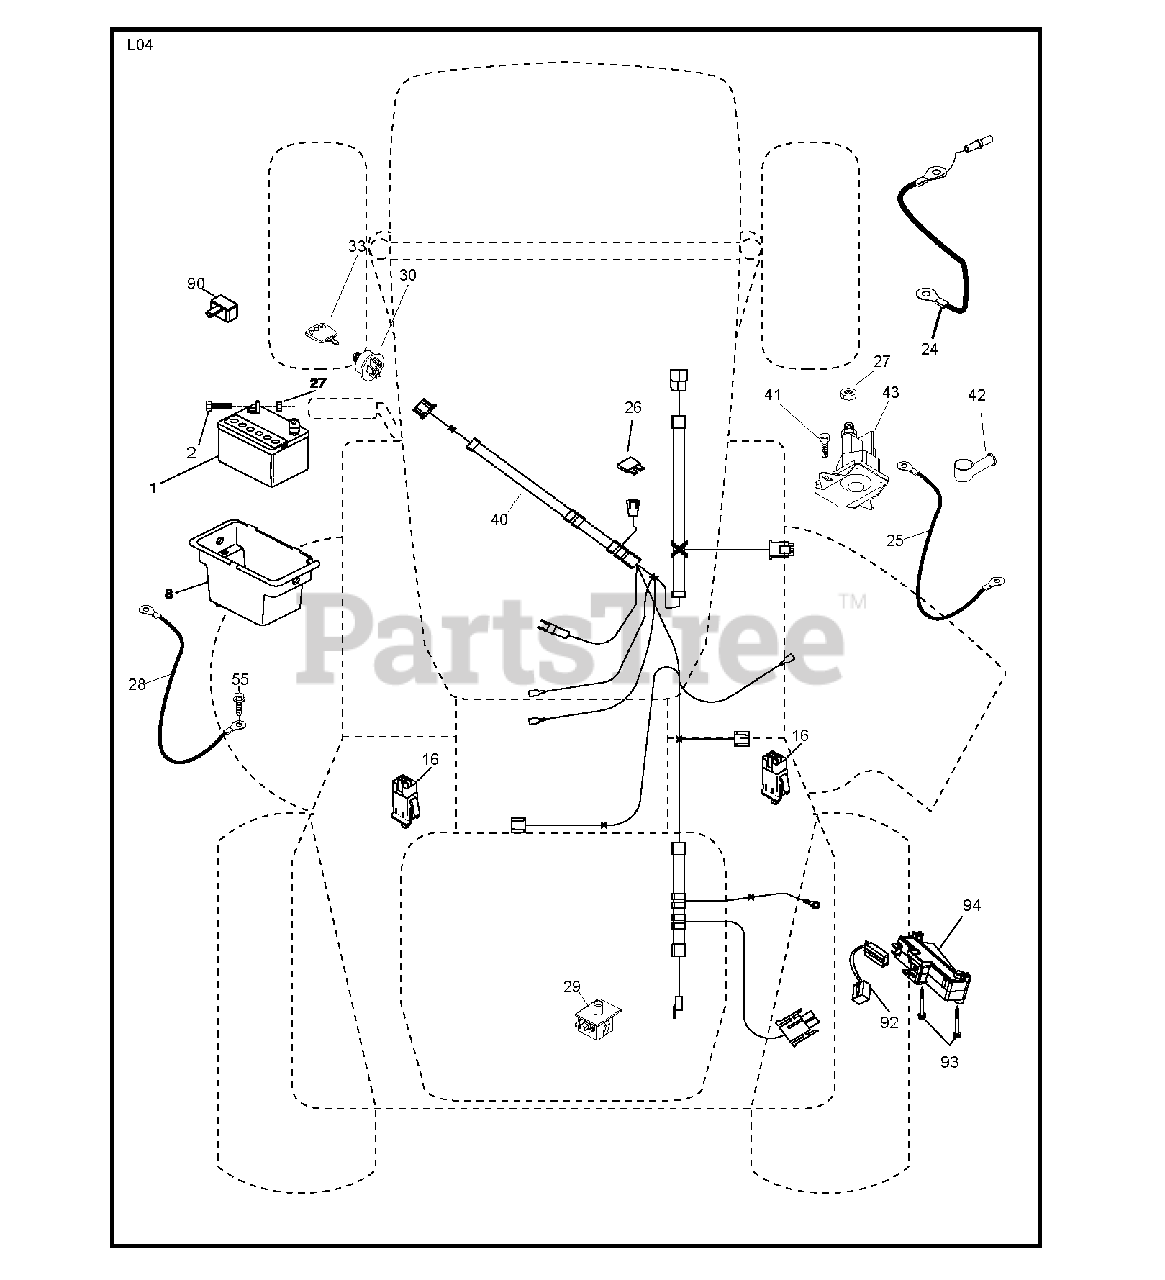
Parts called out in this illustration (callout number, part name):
1	REPL BY 532 12 38-99
8	BOX.BATTERY.FENDER
16	SWITCH INTERLOOK PUSH-IN
24	CABLE.GROUND.REAR.BTRY.8GA.44"
25	CABLE BATTERY 6 GA. 11" RED
27	NUT
28	CABLE GROUND 6 GA. 12" BLACK
29	SWITCH.SEAT.DP W/RAMPS
30	SWITCH.IGN.DELTA.W.LGH.ROS
33	KEY.CHAIN.BLISTER.PACK.GEN.INT
41	Hex Capscrew, 1/4-20
42	TERMINAL COVER
43	SOLENOID.W/BRASS.PLUNG
55	SCREW, 3/8-16X3/4
90	COVER.TERMINAL.BATTERY
92	HARNESS.PIGTAIL.CONSLE
93	SCREW.PLASTITE
94	MODULE.REVERSE.ROS
